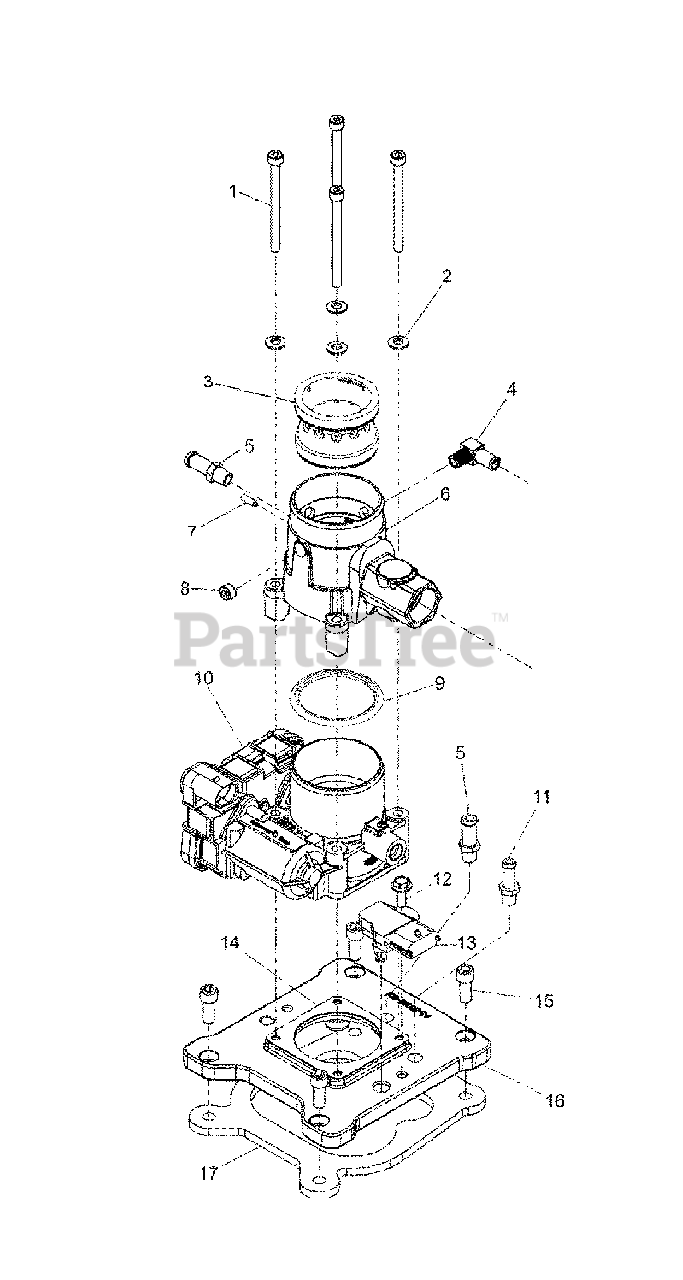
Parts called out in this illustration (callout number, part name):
1	SCREW
2	WASHER
10	THROTTLE BODY
11	FITTING
12	SCREW
15	BOLT
